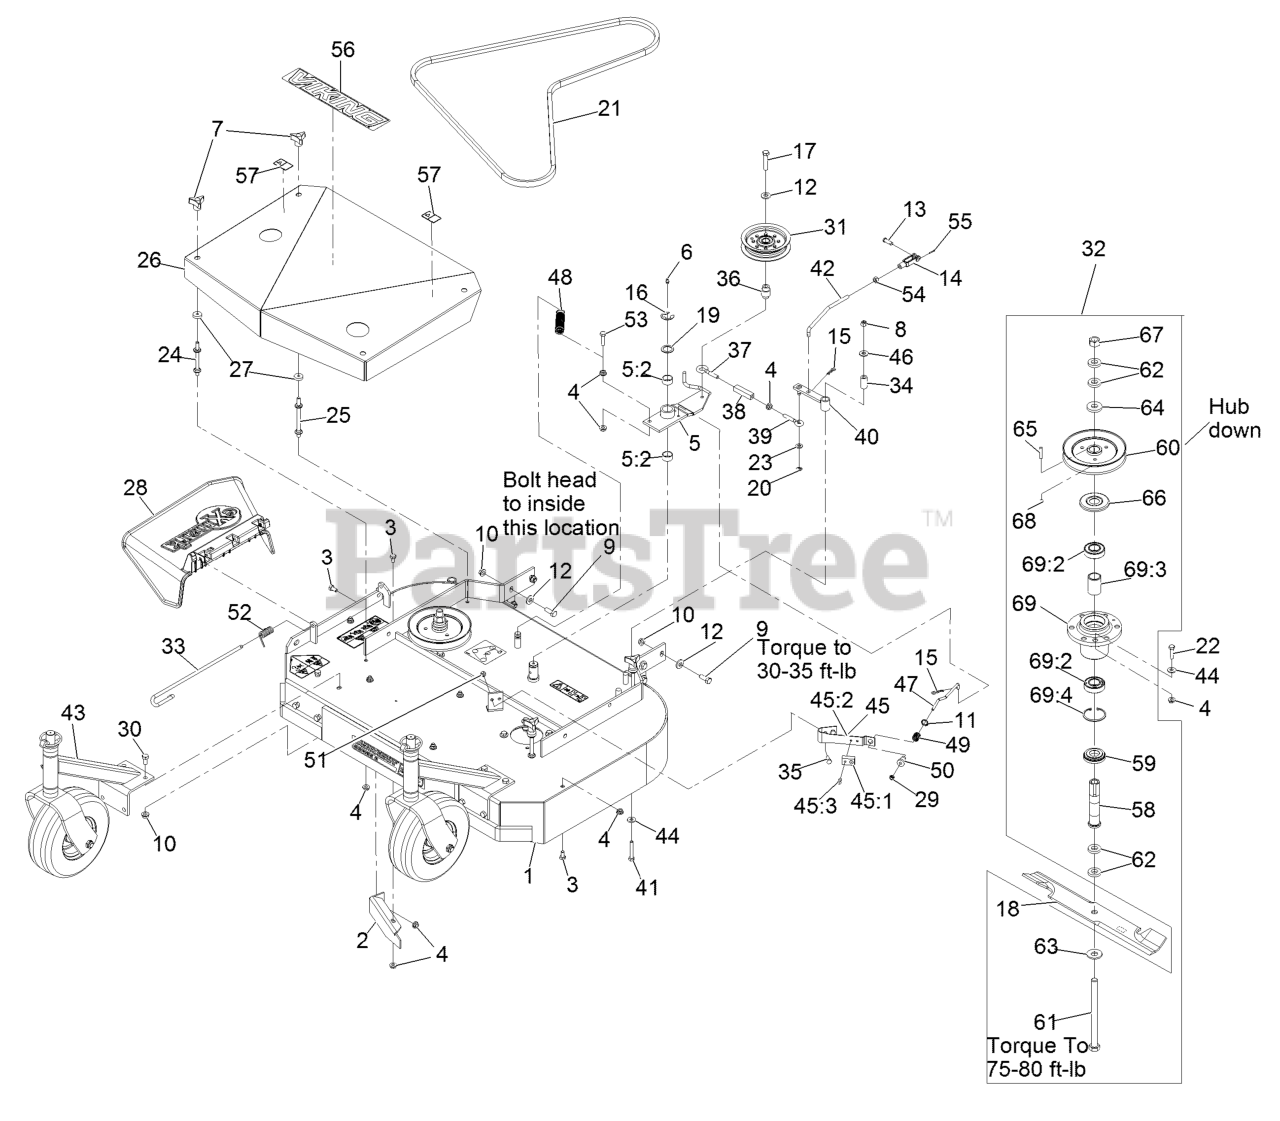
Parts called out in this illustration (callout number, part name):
1	ASM,DECK 36 RIGID
2	BAFFLE-DOGLEG
3	SCREW-HH
5	IDLER ARM ASM
5:2	SLEEVE-BEARING
6	FITTING-GREASE
7	KNOB-3 PRONG
8	NUT-LOCK, NI
9	SCREW-HH
10	NUT-HHF, WHIZ
11	RING-PUSH ON
12	WASHER-BELLEVILLE
13	PIN-CLEVIS
14	YOKE-ADJUSTABLE
15	PIN-COTTER
16	RING-RETAINING, EXT
17	SCREW-HH
19	WASHER-SPINDLE
20	RING-RETAINING, EXT
21	BELT,BLADE VIKING HYD 36
22	SCREW-HH
23	WASHER-PLAIN
24	STUD-SHIELD, BELT (SHORT)
25	STUD-SHIELD, BELT (LONG)
26	ASM,SHIELD W/DECALS 36 VI
28	CHUTE DEFLECTOR XRK M056
29	NUT-LOCK, NI
30	SCREW-HH
32	ASM, CUTTER HOUSING OUTER
33	PIN-CHUTE
34	TUBE-PIVOT
35	SCREW-HH
36	BUSHING-ENGAGEMENT
37	EYEBOLT-THREAD, LH
38	BODY-TURNBUCKLE
39	EYEBOLT-THREAD, RH
40	ARM-ASSIST, 32/36
41	SCREW-HH
42	ARM-LINKAGE, ASSIST
43	ASM-CASTER MNT W/WEIGHT
44	WASHER-SPRING
45	PAD AND SPRING ASM
45:1	PAD-BRAKE
45:3	RIVET-POP
46	WASHER-FLAT
47	ROD-BRAKE
48	SPRING-EXTENSION
49	SPRING-COMPRESSION
50	SPACER-FLANGED
51	NUT-LOCK, NI
52	SPRING, TORSION
53	SCREW-HH, SPECIAL
54	NUT-HEX
55	PIN-COTTER
56	DECAL, VIKING HYDRO MODEL
57	DECAL-WARNING
58	TUBE-SPINDLE, SHORT
59	SPACER-GUARD, BOTTOM
60	SHEAVE
61	SCREW-CAP, HH
63	WASHER-SPRING
64	WASHER-RETAINER, SHEAVE
66	GUARD-BEARING, TOP
67	NUT-HEX
68	SETSCREW
69	KIT, CUTTER HOUSING
69	Asm, Cutter Housing W/Bearings
69:2	BEARING-JACKSHAFT
69:3	SPACER-BEARING
69:4	RING-SNAP
